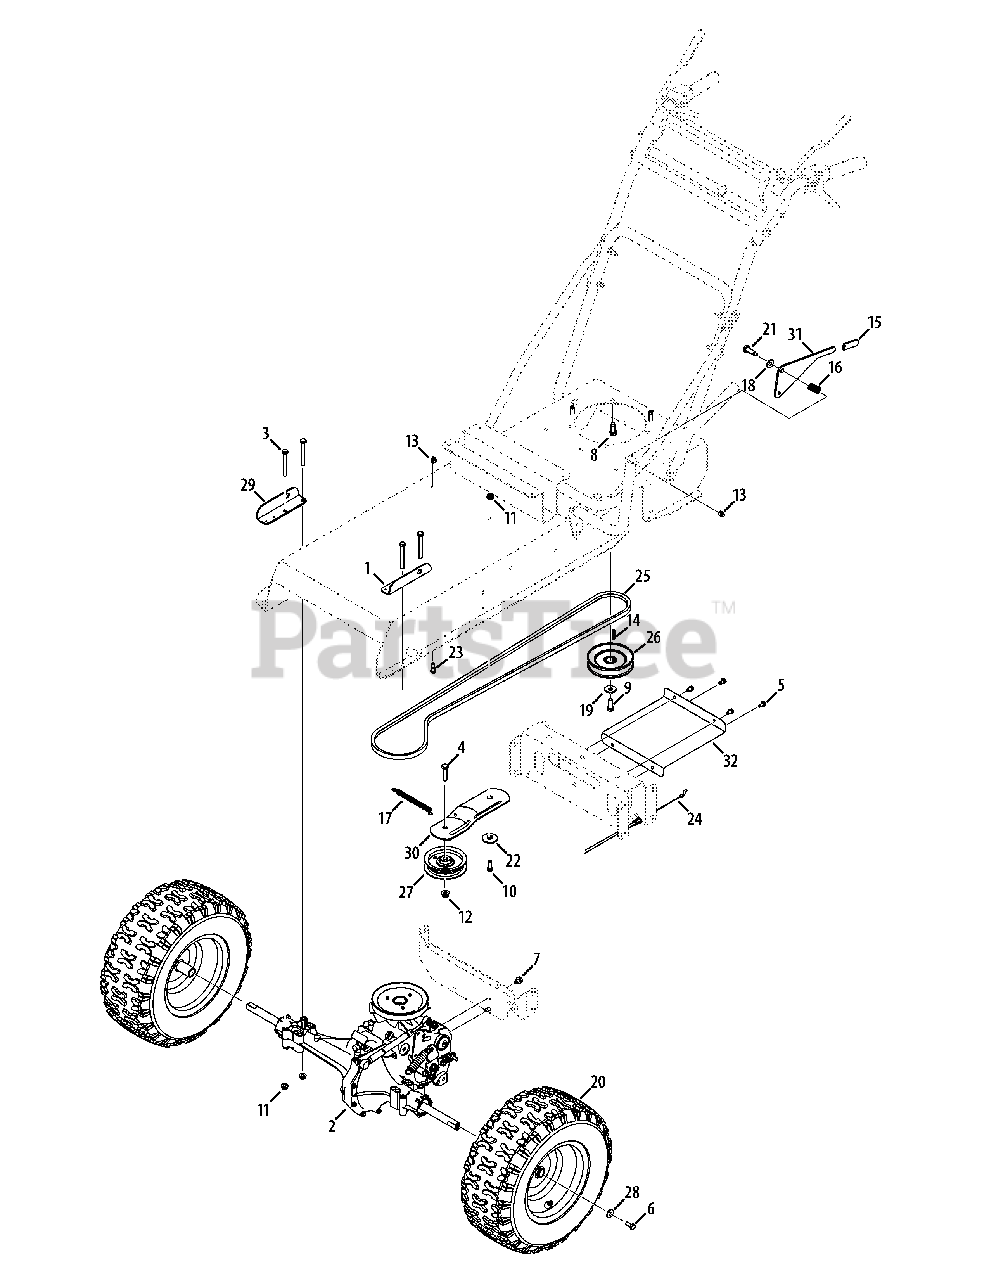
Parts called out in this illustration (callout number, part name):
1	Support Bracket, LH
2	Transmission Assembly w/ Damper
2	Cylinder, Damper
2	Spring, .75 OD X 3.240
3	Hex Head Screw, ....-18 x 2.75
4	Hex Head Screw, 3..-16 x 1.50
5	Screw, .-20 x 0.500
6	Hex Head Screw, ....-24 x .750
7	Screw, ....-18 x 0.500
8	Screw, 3..-16 x 1.000
9	Hex Head Screw, 3..-24 x 1.00
10	Hex Head Screw, ....-18 x .875
11	Flangelock Nut, ....-18
12	Flangelock Nut, 3..-16
13	Cap Lock Nut, .-20
14	Square Key, 3... x 1.00
15	Shift Handle Grip
16	Compression Spring, .39 x .60 x .88
17	Extension Spring, .55 DIA x 6.25 LG
18	Washer, Flat, .385 x .87 x .06
19	Washer, Bell, .396 x 1.140 x .095
20	X-Trac Wheel, Complete, 16 x 6.5 x 8
21	Screw, Shield, .374 DIA. x 1.05 LG.
22	Spacer, Shoulder, .5000 x .1475
23	Screw, Shoulder, .-20 x .31 x .50
24	Transmission Cable
25	V-Belt, 4L x 78 LG POLY
26	Engine Pulley
27	Idler Pulley, 3.50 DIA.
28	Washer, Bell, .340 x .872 x .060
29	Support Bracket, RH
30	Idler Bracket
31	Transmission Release Bracket
